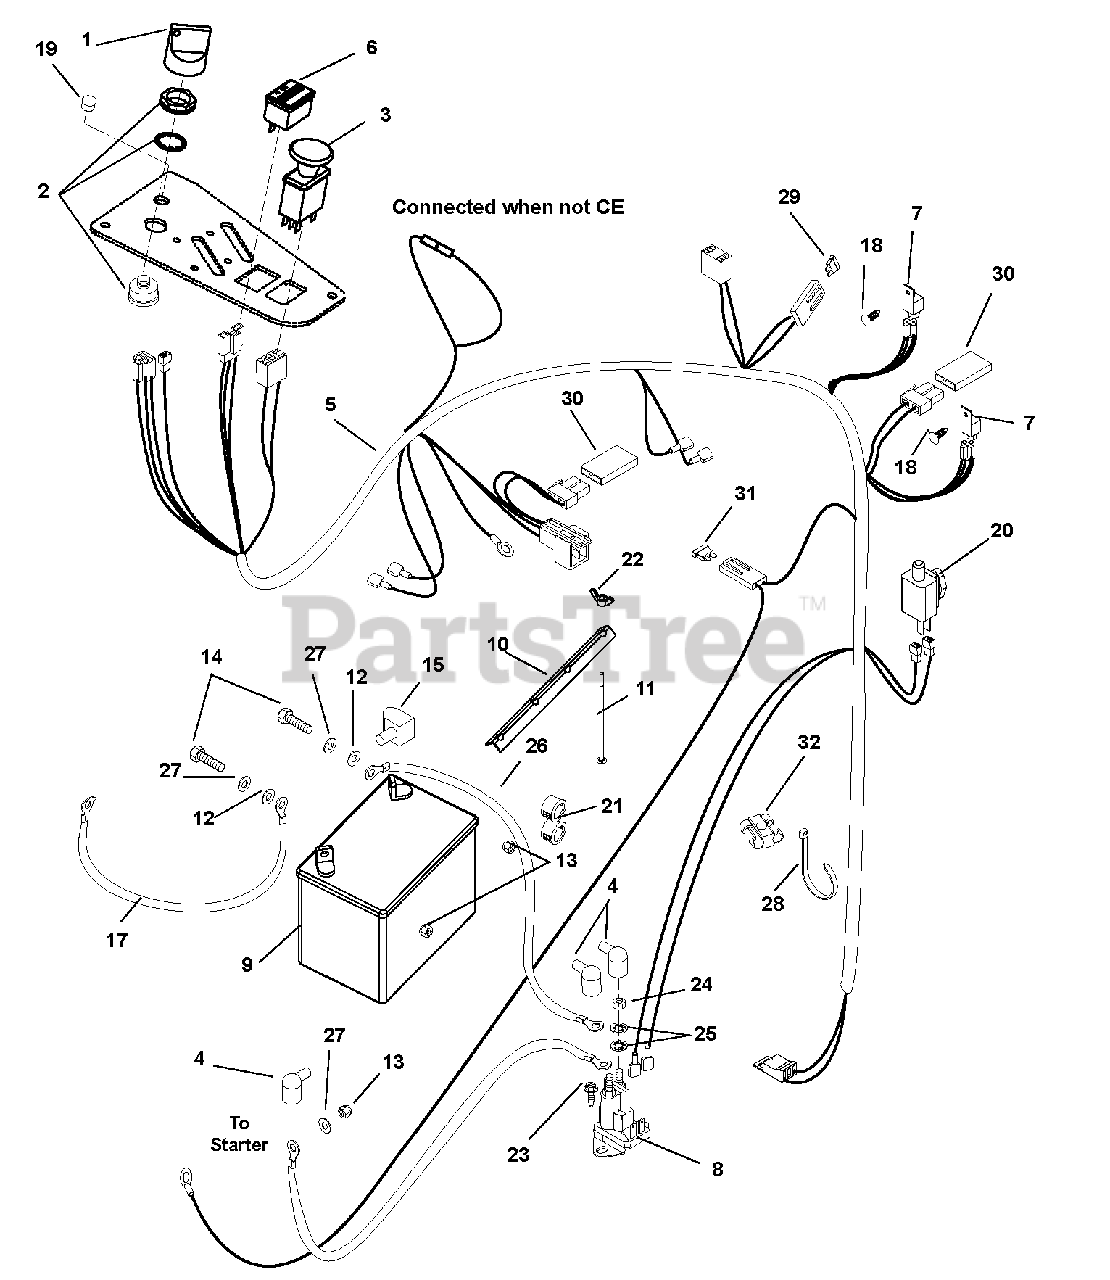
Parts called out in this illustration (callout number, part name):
1	Key, with Shield
2	Switch, Ignition
3	Switch, Clutch
4	Boot, Eyelet Terminal
5	Harness, CZ Remote SOL.
6	Hour Meter, with Maintenance
7	Relay, Sealed with Diode
8	Solenoid
10	Hold Down
11	Bolt, Round Head Square Neck .25-20 x 7.50
12	Washer, Flat Steel .281 x .620 x .065
13	Nut, Hex .25-20
14	Bolt, Hex .25-20 x .75 Grade 5
15	Insulator
16	Cable, Positive Battery 9.00"
17	Cable, Negative Battery
18	Rivet, .25 Nylon Panel
19	Plug, Hole .50 Diameter
20	Switch, Single Pole (N.O.) – Brake Switch
21	Bushing, Panel Snap .687 x .875 x .56
22	Nut, Locking Wing .25-20
23	Screw, Tapping .25-20 x .50 Hex Washer Head
24	Nut, Jam .31-24
25	Washer, Star Washer .31 x .078 Regular
26	Cable, Starter
27	Washer, Lock .25 x .062
28	Tie, Cable LG 5.50
29	Fuse 20AMP
30	Diode, Connector Shell
31	Fuse, 25 AMP
32	Clip,T,.31-.38
